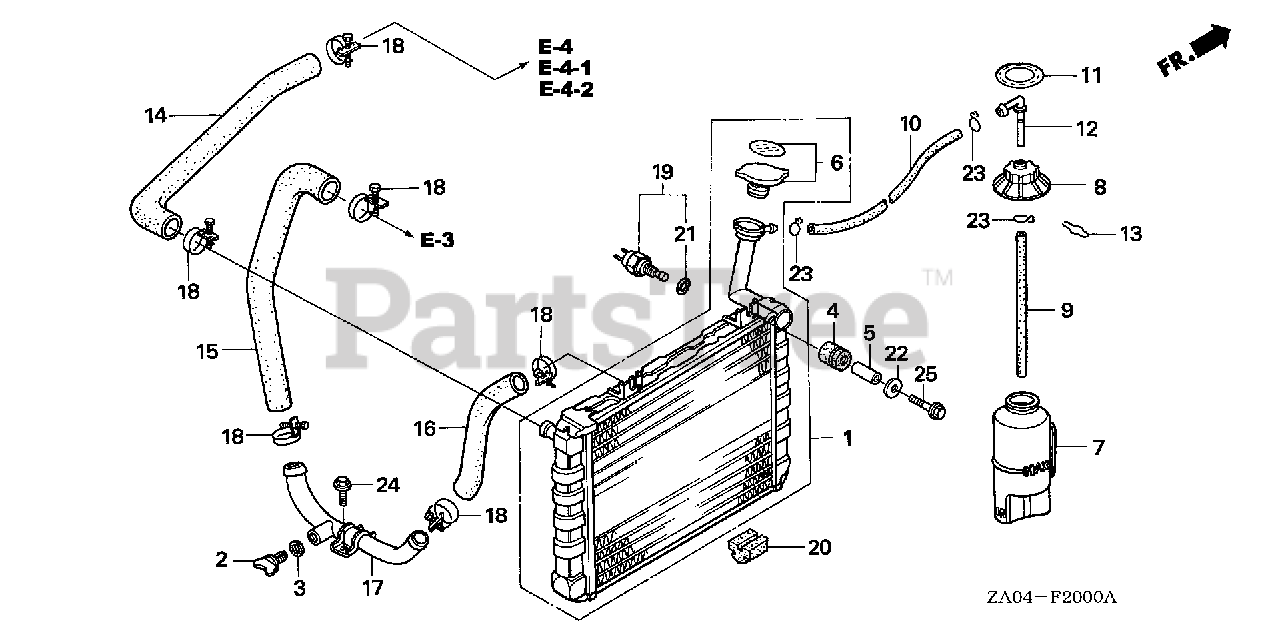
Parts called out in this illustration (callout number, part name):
1	RADIATOR (TOYO)
2	PETCOCK, DRAIN (DENSO)
3	GASKET, DRAIN
4	RUBBER, RADIATOR MOUNTING
5	COLLAR, DISTANCE (NOT AVAILABLE)
6	CAP, RADIATOR (DENSO)
7	TANK, RESERVE
8	CAP, RESERVE TANK
9	HOSE, RESERVE TANK
10	TUBE, RESERVOIR TANK
11	MARK, RESERVE TANK
12	JOINT, RESERVE TANK
13	CLIP, RESERVE TANK JOINT
14	HOSE, WATER (UPPER)
15	HOSE, WATER (LOWER)
16	HOSE B, WATER (LOWER)
17	PIPE, JOINT (LOWER)
18	CLIP, WATER HOSE
19	SWITCH, THERMOSTAT
20	RUBBER, RADIATOR MOUNTING
21	O-RING (13.5X1.4)
22	WASHER, WHEEL (6MM)
23	CLIP, TUBE (C11)
24	BOLT, FLANGE (6X12)
25	BOLT, FLANGE (6X28)
